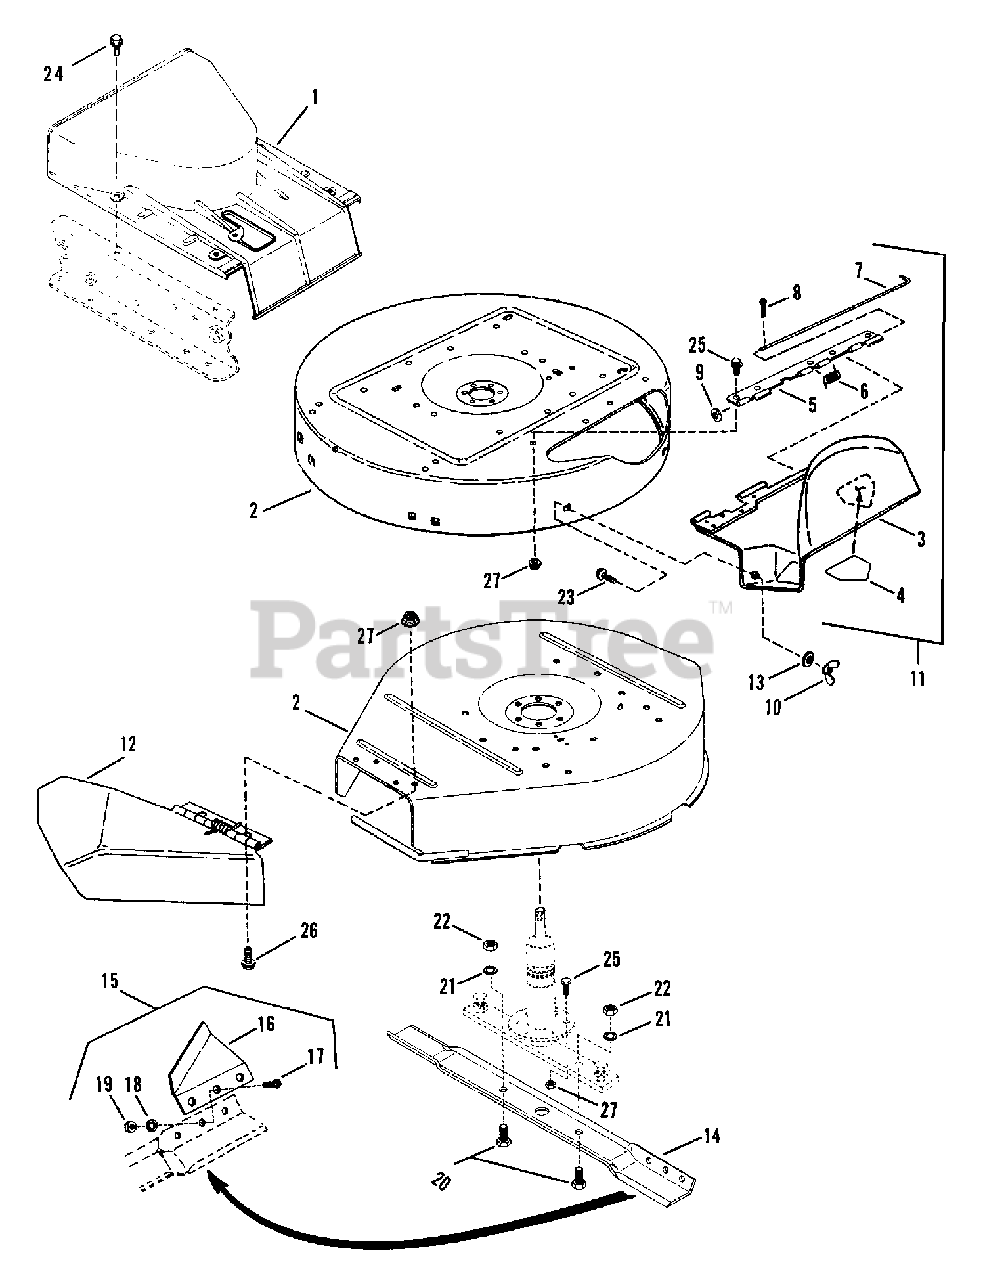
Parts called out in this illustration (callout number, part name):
1	COVER, Spindle
2	25" DECK (Includes decals)
2	26" DECK (Includes decals & deflector)
2	28" DECK (Includes decals)
2	30" DECK (Includes decals & deflector)
3	DEFLECTOR, Discharge (25" Deck)
3	DEFLECTOR, Discharge (28" & 33" Deck)
4	DECAL, Danger (Cut Finger)
5	HINGE, Deflector
6	SPRING, Hinge
7	PIN, Hinge
8	PIN, 3/32 x 3/4" Cotter
9	WASHER, 1/4 Flat
10	NUT, 5/16-18 Wing
11	ASSEMBLY, Discharge (25" Deck)
11	ASSEMBLY, Discharge (28" Deck)
12	DEFLECTOR, Discharge (26" & 30" Decks)
13	WASHER, 5/16 Flat
14	25" BLADE
14	26" BLADE
14	28" BLADE
14	30" BLADE
15	AIR LIFT KIT, Hi-Vac
16	AIR LIFT, Hi-Vac (3 hole)
17	SCREW, 5/16-24 x 11/16" Machine
18	WASHER, 5/16-24 Internal Tooth Lock
19	NUT, 5/16-24 Hex
20	SCREW, 1/2-20 x 1" Hex Head Cap
21	WASHER, 1/2 Internal Tooth Lock
22	NUT, 1/2-20 Hex Jam
23	BOLT, 5/16-18 x 3/4" Short Neck Carriage
24	SCREW, 1/4-20x 5/8" Self-Tapping
25	BOLT, 3/8-16 x 3/4" Hex Flange Lock
26	BOLT, 5/16-18 x 1/2" Hex Flange Lock
27	NUT, 3/8-16 Hex Flange Lock
